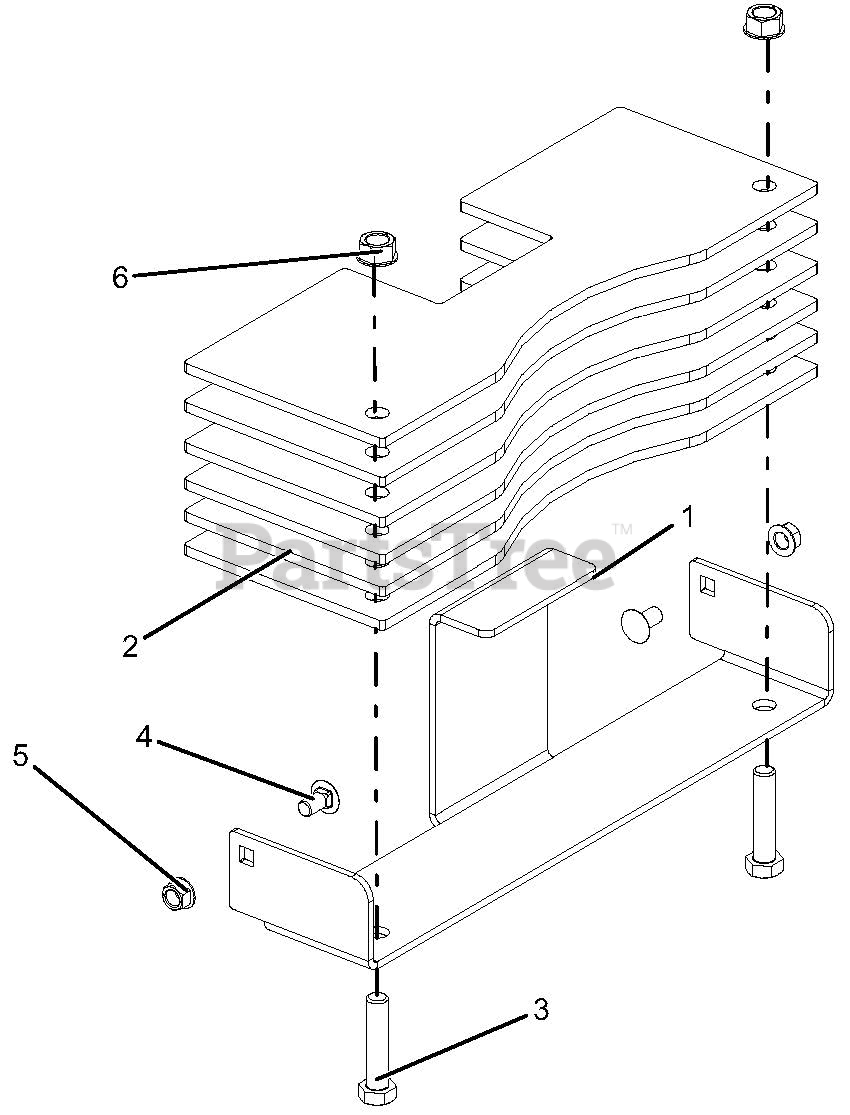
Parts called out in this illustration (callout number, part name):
1	BRACKET, WEIGHT -BAGGER
2	WEIGHT, BAGGER
3	BLT-HEX .50-13X2.25 GR5 YWZC
4	BLT-RDHDSQNK .38-16X.75 G5YZ
5	NUT-LK-TOP-FLG .38-16 YWZC
6	NUT-LK-TOP-FLG .50-13 YWZC
